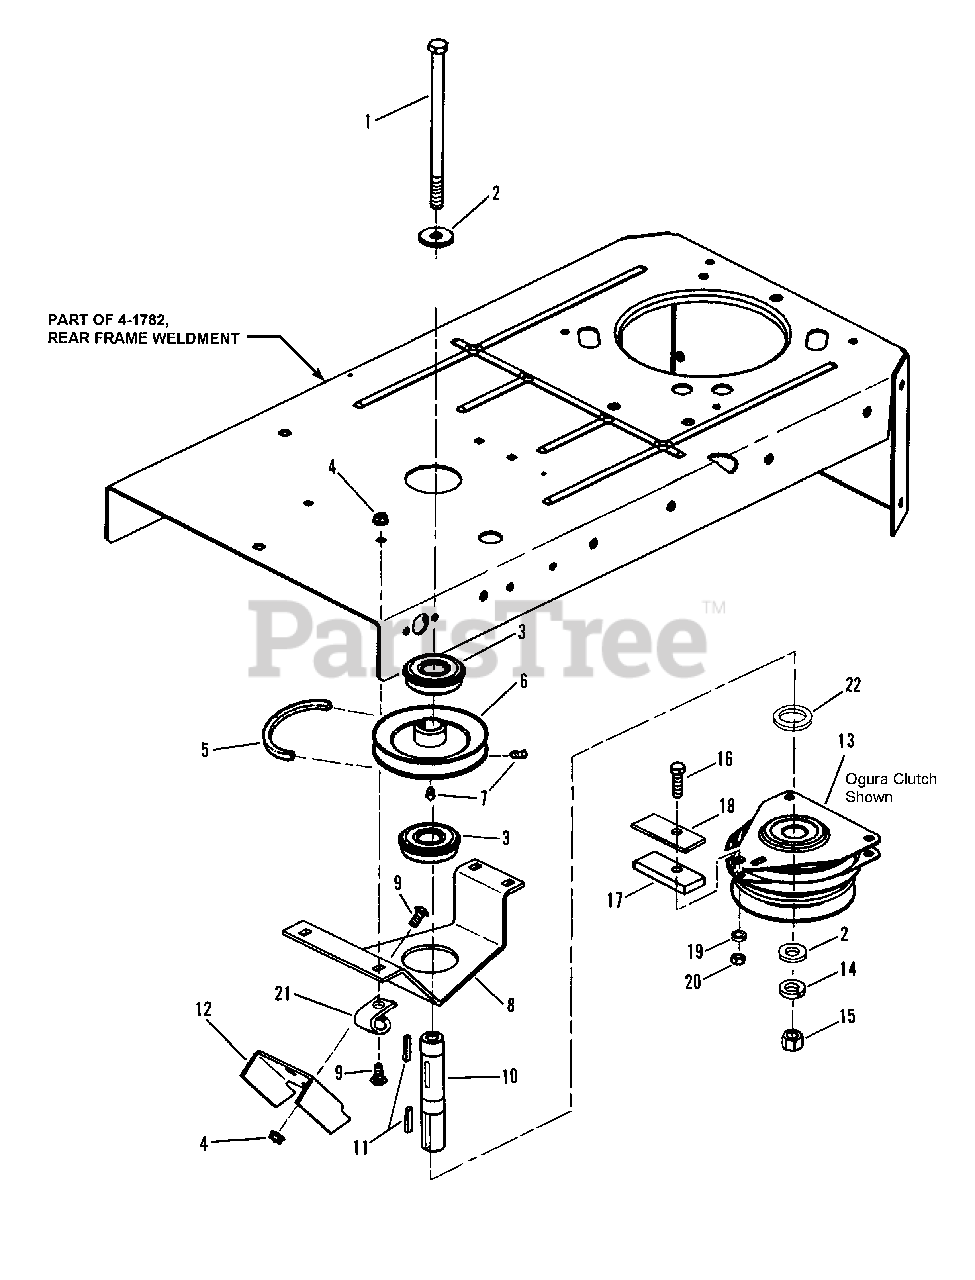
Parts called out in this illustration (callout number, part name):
1	SCREW, 7/16-20 x 8" Hex Head Cap
2	WASHER, 7/16 x 1" O.D. Flat
3	BEARING, 6305 w/Snap-Ring
4	NUT, 5/16-1 8, Grade 5
5	V-BELT, Drive
6	PULLEY, Jackshaft
7	SETSCREW, 1/4-20 x 1/2" w/Patch
8	SUPPORT, Jackshaft
9	BOLT, 5/16-18 x 3/4 Carriage, Grade 5
10	JACKSHAFT
11	KEY, 1/4 x 1" Square
12	BRACKET, Anti-Rotate (Ogura)
13	CLUTCH, Electric (Ogura) 33" Models
14	WASHER, 7/16" Split Lock
15	NUT, 7/16-20, Grade B
16	SCREW, 5/16-18 x 1-1/4" ,Hex Head Cap, Grade 5
17	BUMPER, Electric Clutch
18	WASHER, Rectangular Steel
19	WASHER, 5/16" Split Lock
20	NUT, 5/16-18, Grade 5
21	CLIP, Wire, 7/16
22	WASHER (Ogura Clutch) 1.312" OD, .125" Thick
